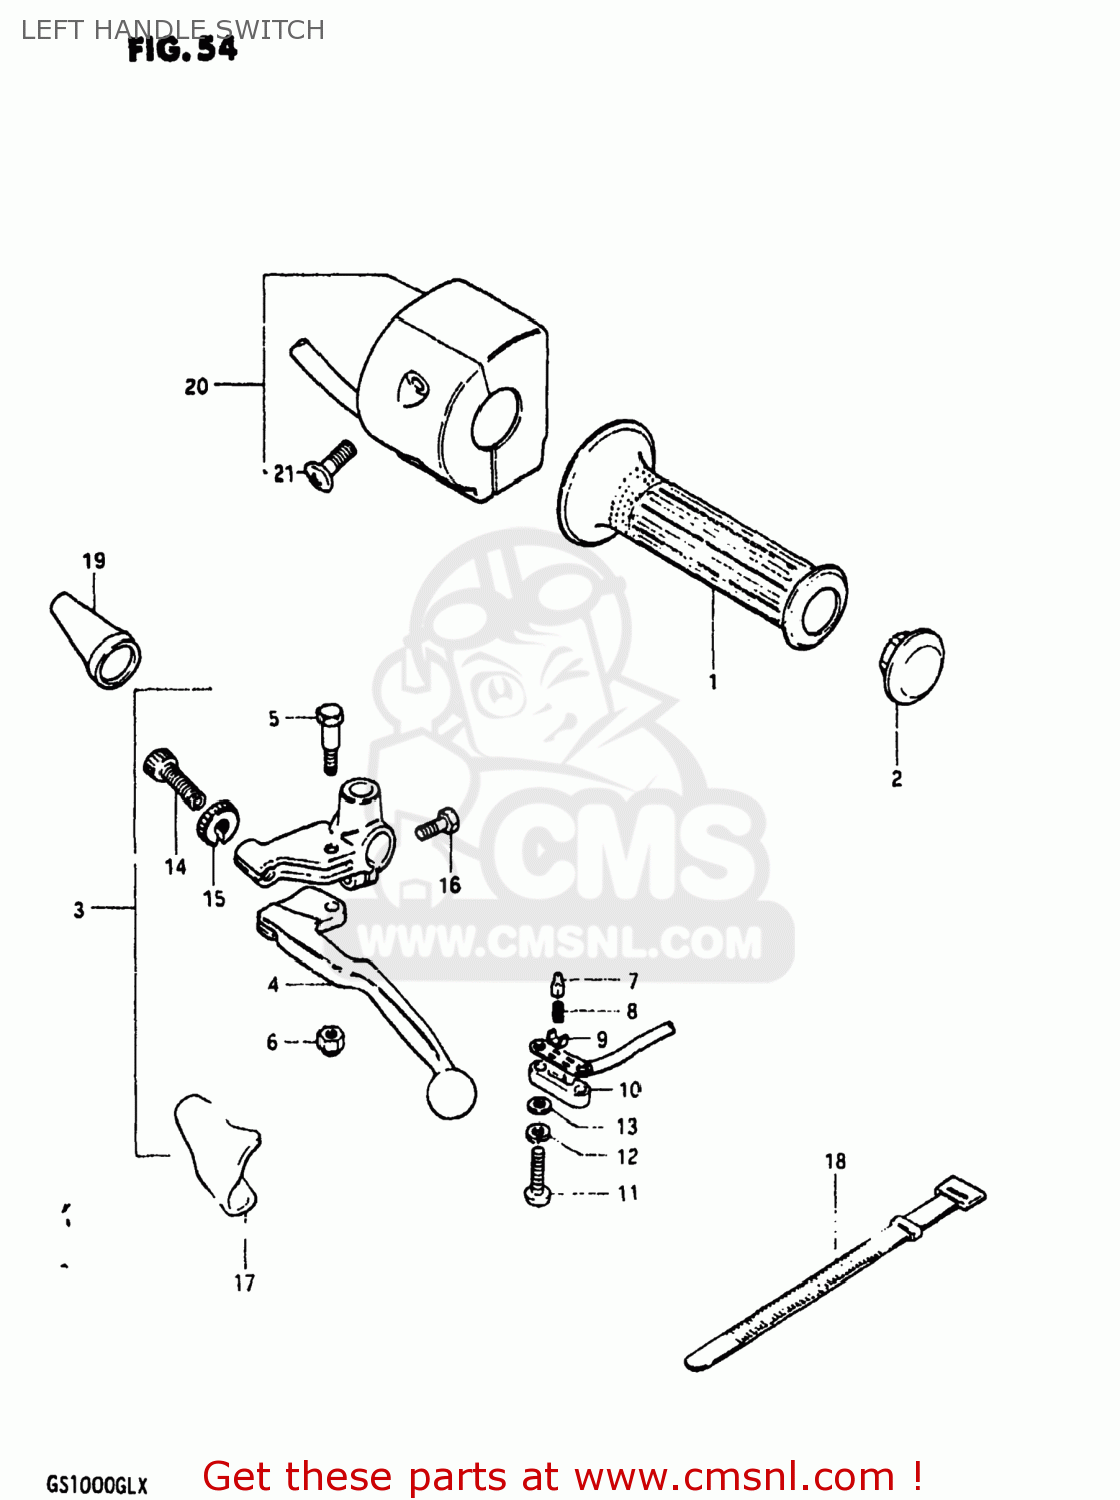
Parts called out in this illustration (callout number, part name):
1	GRIP,LEFT
2	CAP,GRIP END
3	LEVER ASSEMBLY
4	LEVER,CLUTCH
5	BOLT,LEVER
6	NUT 6MM
7	HOLDER
8	SPRING
9	PLATE
10	COVER,FR BK TERMINAL BASE
11	SCREW
12	LOCK WASHER
13	WASHER
14	ADJUSTER,CABLE
15	NUT,CABLE ADJUSTER
16	BOLT,CLUTCH LEVER HOLDER
17	COVER,CLUTCH LEVER
18	CLAMP(L:120)
19	BOOT,CLUTCH CABLE
20	SWITCH ASSEMBLY,HANDLE,LEFT
21	SCREW
